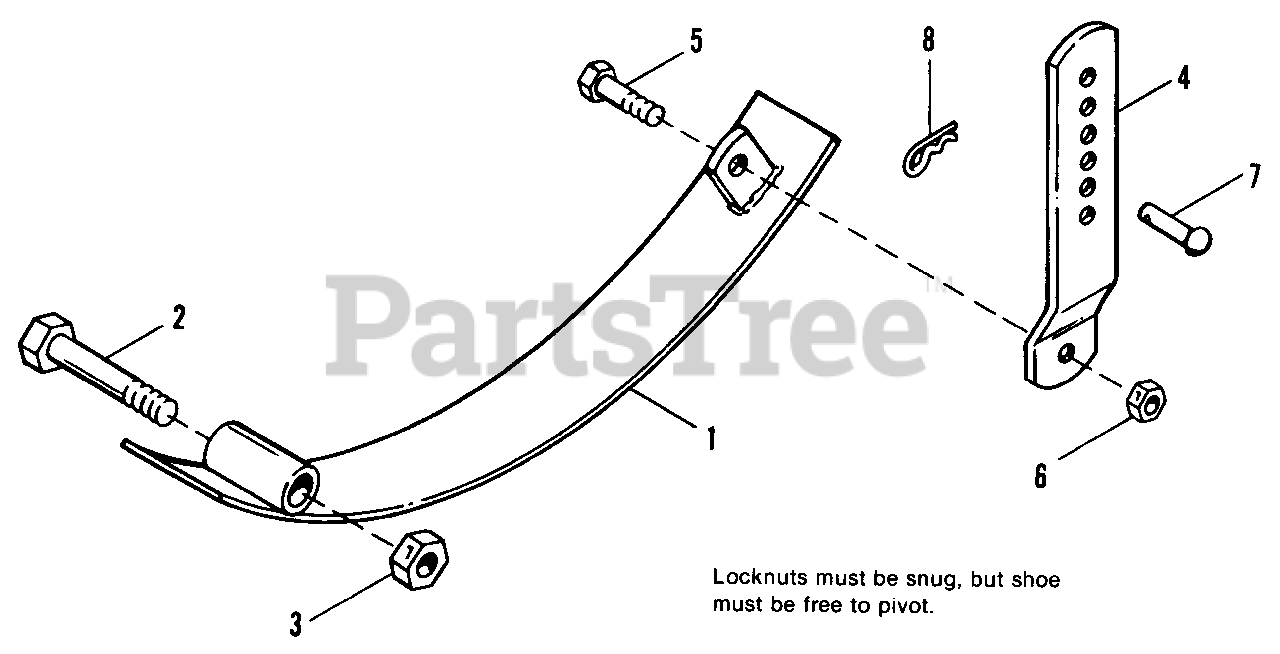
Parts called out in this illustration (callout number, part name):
1	SKID ASSY.
2	CAPSCREW, Hex Hd., 5/8-11 x 3
3	LOCKNUT, Hex, 5/8-11
4	BRACKET, Adjusting
5	CAPSCREW, Hex Hd., 3/8-16 x 1
6	LOCKNUT, Hex, 3/8-16
7	PIN, Yoke, 3/8
8	CLIP, Spring
